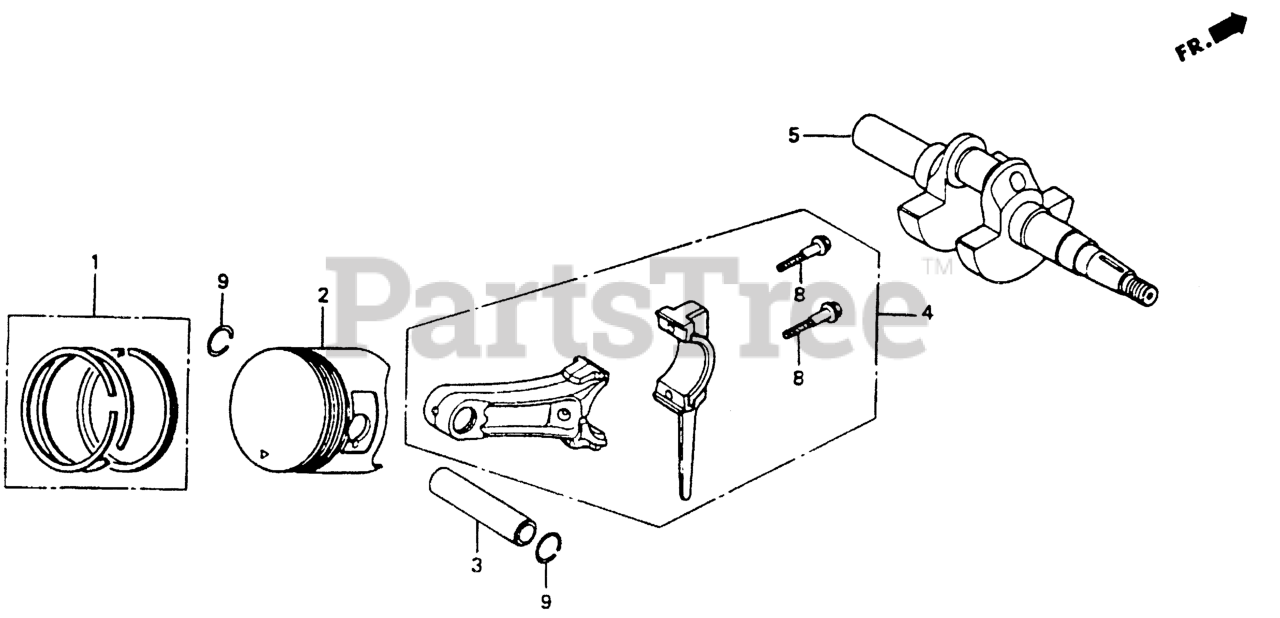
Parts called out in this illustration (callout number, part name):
1	RING SET, PISTON (STD)
1	RING SET, PISTON (OS 0.25) (NIPPON) Use up to Engine SN 2120317.
1	RING SET, PISTON (OS 0.25) (TEIKOKU) Use up to Engine SN 2120317.
1	RING SET, PISTON (OS 0.50) (NIPPON) Use up to Engine SN 2120317.
1	RING SET, PISTON (OS 0.50) (TEIKOKU) Use up to Engine SN 2120317.
1	RING SET, PISTON (OS 0.75) (NIPPON) Use up to Engine SN 2120317.
1	RING SET, PISTON (OS 0.75) (TEIKOKU) Use up to Engine SN 2120317.
1	RING SET, PISTON (OS 0.25)
1	RING SET, PISTON (OS 0.50) Use from Engine SN 2582392.
1	RING SET, PISTON (OS 0.50) (TEIKOKU)
1	RING SET, PISTON (0.75) (NIPPON) (NA USE ALT:13013-ZE1-014)
1	RING SET, PISTON (0.75) (TEIKOKU)
2	PISTON (STD)
2	PISTON (0.25)
2	PISTON (OS 0.25) Use up to Engine SN 2582392.
2	PISTON (0.50)
2	PISTON (OS 0.50)
2	PISTON (0.75) Use up to Engine SN 2120317.
2	PISTON (0.75)
3	PIN, PISTON
4	ROD ASSY., CONNECTING (0.25 LOWER SIZE) (NOT AVAILABLE)
4	ROD ASSY., CONNECTING
5	CRANKSHAFT (WB-TYPE)
8	BOLT, CONNECTING ROD
9	CLIP, PISTON PIN (18MM)
